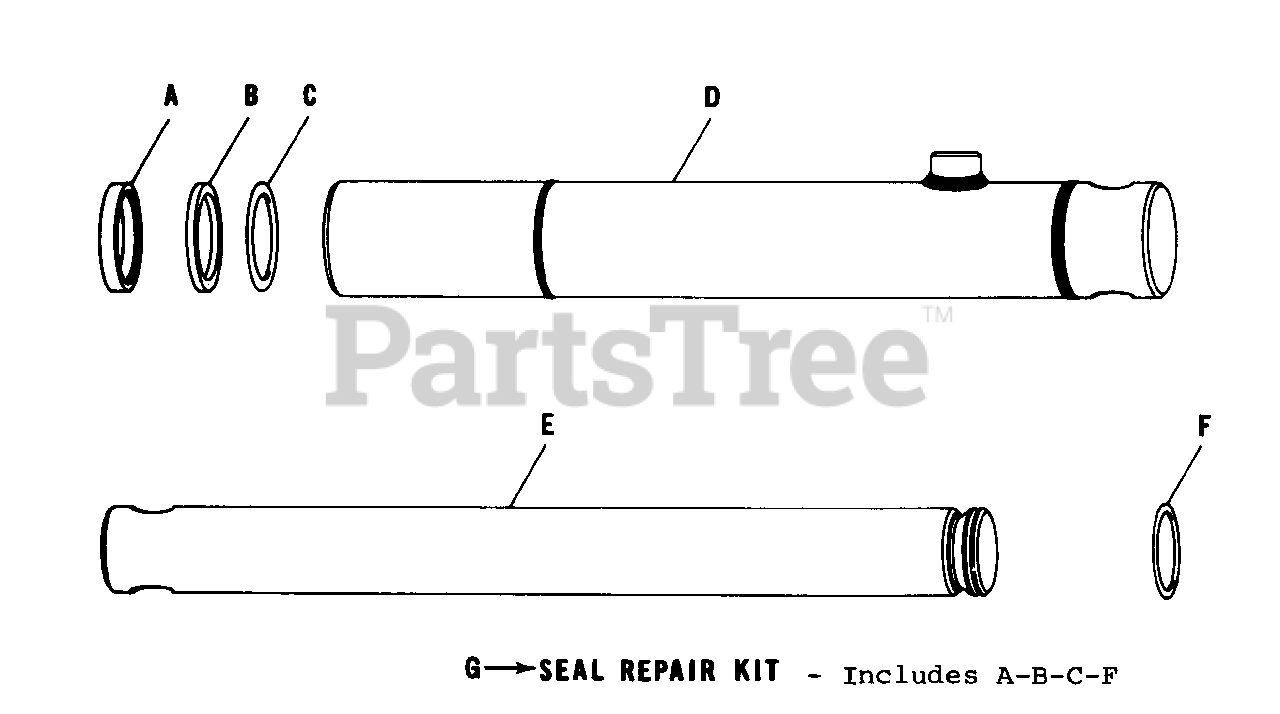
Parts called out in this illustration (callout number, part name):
A	Rod Wiper & Seal
B	Back-Up Washer
D	Cylinder Tube Ass'y.
E	Piston Rod
F	Lock Ring
G	Major Seal Repair Kit
